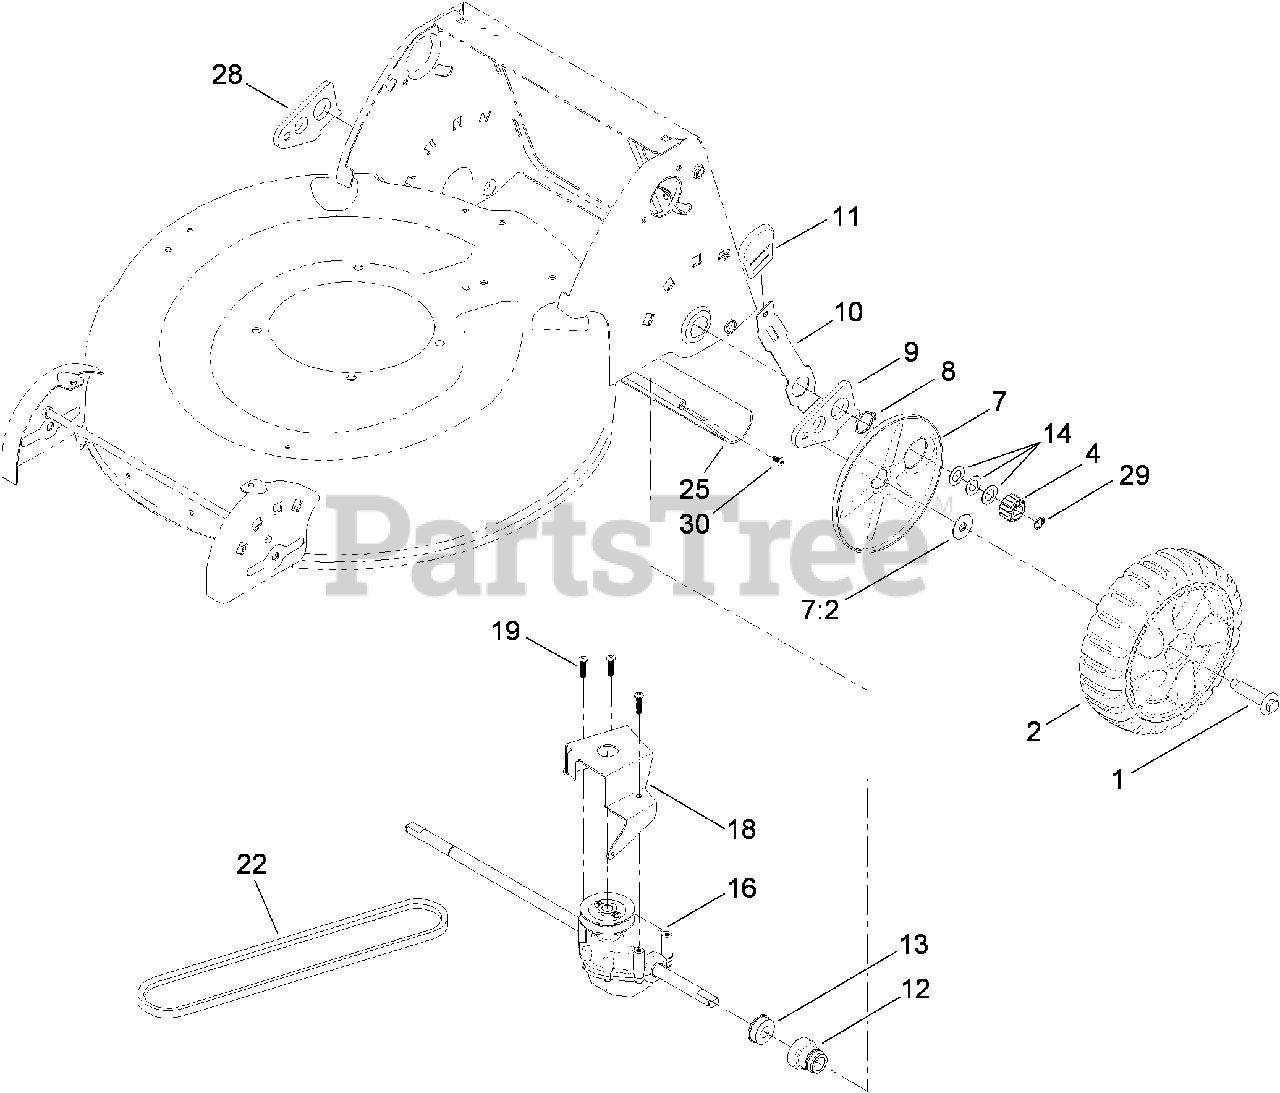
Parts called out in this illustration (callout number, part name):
1	BOLT-SHOULDER
2	REAR WHEEL ASM
4	PINION
7	WHEEL COVER ASM
7:2	WASHER-STEPPED
8	RING-RETAINING
9	ARM-REAR PIVOT, LH
10	ARM-SPRING, REAR
12	RETAINER-BEARING, HOC
13	BEARING-BALL
14	WASHER-PLAIN
16	TRANSMISSION ASM
18	BRACKET-TRANSMISSION
19	SCREW-PLASTITE
25	SHIELD-TRAILING
28	ARM-REAR PIVOT, RH
29	RING-RETAINING
30	SCREW-PTH
